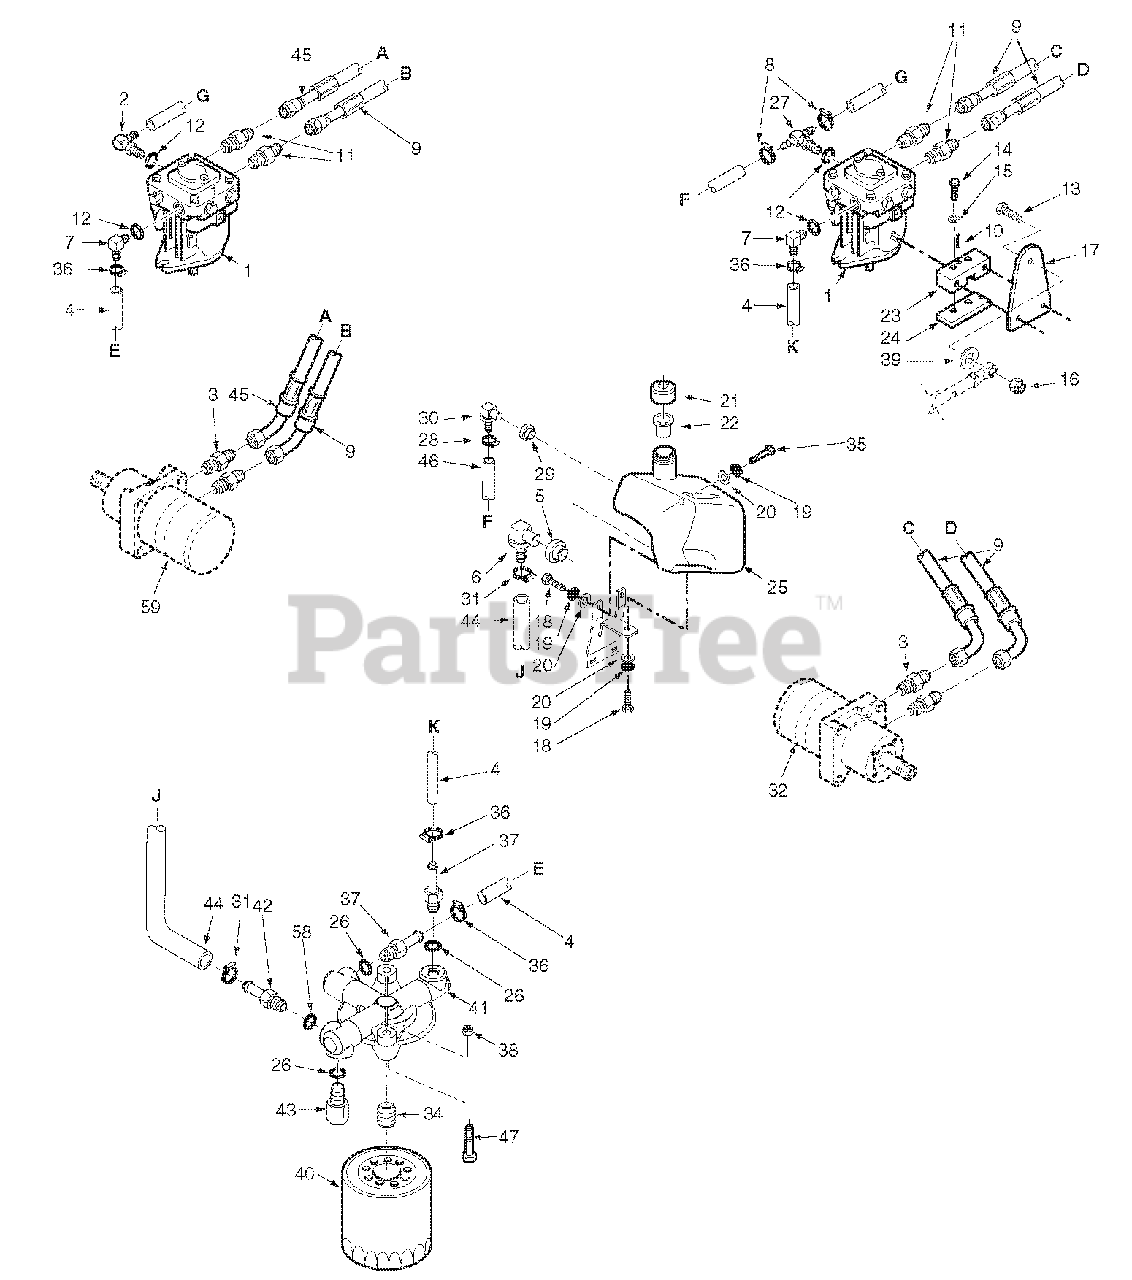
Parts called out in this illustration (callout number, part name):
1	Pump, BDP-10A-316 (LH)
1	Pump, BDP-10A-419 (RH)
2	Elbow, 90 Degree 9/16" O-Ring x 3/8" Hose
3	Fitting, 1/2" JIC x 5/8" O-Ring
4	Hose, 3/8" Pushlock (Specify length)
5	Bushing
6	Fitting
7	Elbow, 90 Degree 9/16" O-Ring x 3/8" Hose
8	Hose Clamp, .69" Dia.
9	Hose Assembly
10	Roll Pin
11	Fitting, 1/2" JIC x 1/2" O-Ring
12	O-Ring
13	Bolt, Hex Head 3/8-16 x 1-1/2"
14	Bolt, Hex Head 1/4-20 x 1-1/4"
15	Lockwasher
16	Nut, Elastic Stop 3/8-16
17	Control Lever
18	Bolt, Hex Head 5/16-18 x 3/4"
19	Lockwasher, 5/16"
20	Flatwasher, 5/16-.375 x .875 x .083
21	Cap, Hydraulic Tank
22	Insert, Filler Neck
23	Control Block
24	Clamp Plate
25	Hydraulic Tank Assembly w/Fittings
26	O-Ring, 9/16"
27	Tee Fitting, O-Ring to Barb
28	Clamp, .69" Max. / .25" Min. Dia.
29	Bushing
30	Elbow, 0.38" Hose
32	Wheel Motor, Parker
33	O-Ring, 3/4"
34	Nipple, Oil Filter 1.0-12 UNF-2A x 1-1/4"
35	Bolt, Hex Head 5/16-18 x 1-1/2"
36	Clamp, .69" Max. / .25" Min. Dia.
37	Fitting, 9/16" O-Ring x 3/8" Hose
38	Nut, Serr. Flange 5/16-18
39	Flatwasher, 3/8-.391 x .938 x .105"
40	Oil Filter
41	Filter Head Assembly
42	Fitting, 3/4" O-Ring x 3/8" Hose
43	Plug, 9/16-18 O-Ring
44	Hose, Filter Inlet
45	Hose Assembly
46	Hose, 3/8" Pushlock 15" Long
47	Bolt, Hex Head 5/16-18 x 2"
